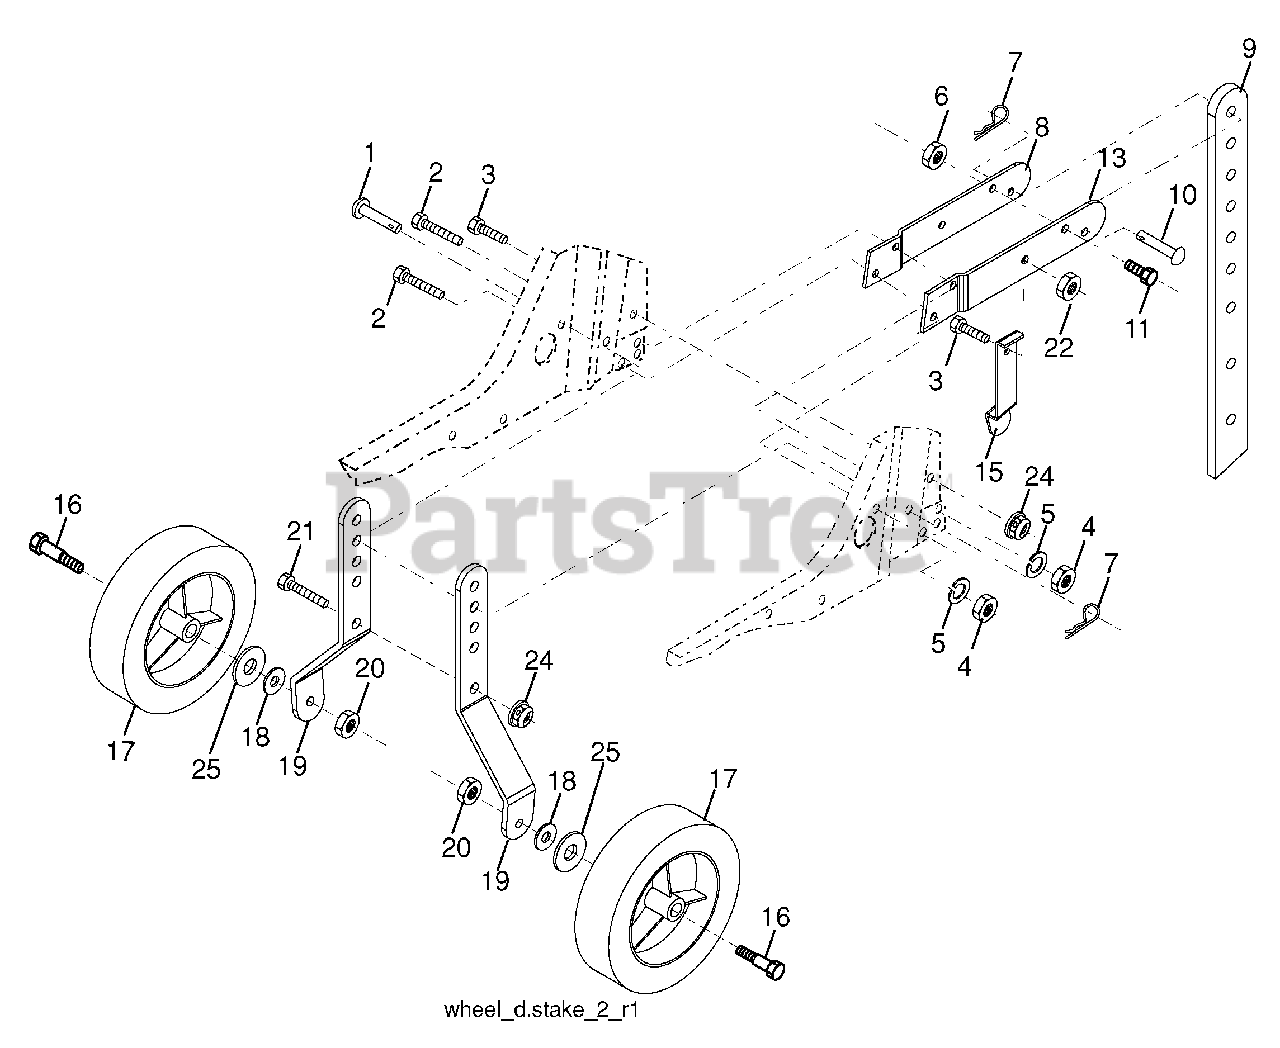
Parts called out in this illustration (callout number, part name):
1	Pin, Clevis
2	Bolt, Hex Head 5/16-18 x 1-1/4
3	Bolt, Hex Head 5/16-18 x 3/4
4	Nut, Hex 5/16-18
5	Washer, Lock 5/16
6	Locknut, Washer Insert 3/8-16
7	Clip, Hairpin
8	Support, Depth Stake, R.H.
9	Stake, Depth
10	Pin, Clevis
11	Bolt, Hex Head 3/8-16 x 1-3/4
13	Support, Depth Stake, L.H.
15	Spring, Stake
16	Bolt, Shoulder
17	Wheel
18	Washer 13/32 x 13/16 x 11 Ga.
19	Bracket, Wheel
20	Nut, Hex, Crownlock 3/8-16
21	Bolt, Hex Head 5/16-18 x 1
22	Locknut, Washer Insert 5/16-18
24	Nut, Hex, Flangelock
25	Washer, 17/32 x 7/8 x 16 Ga.
